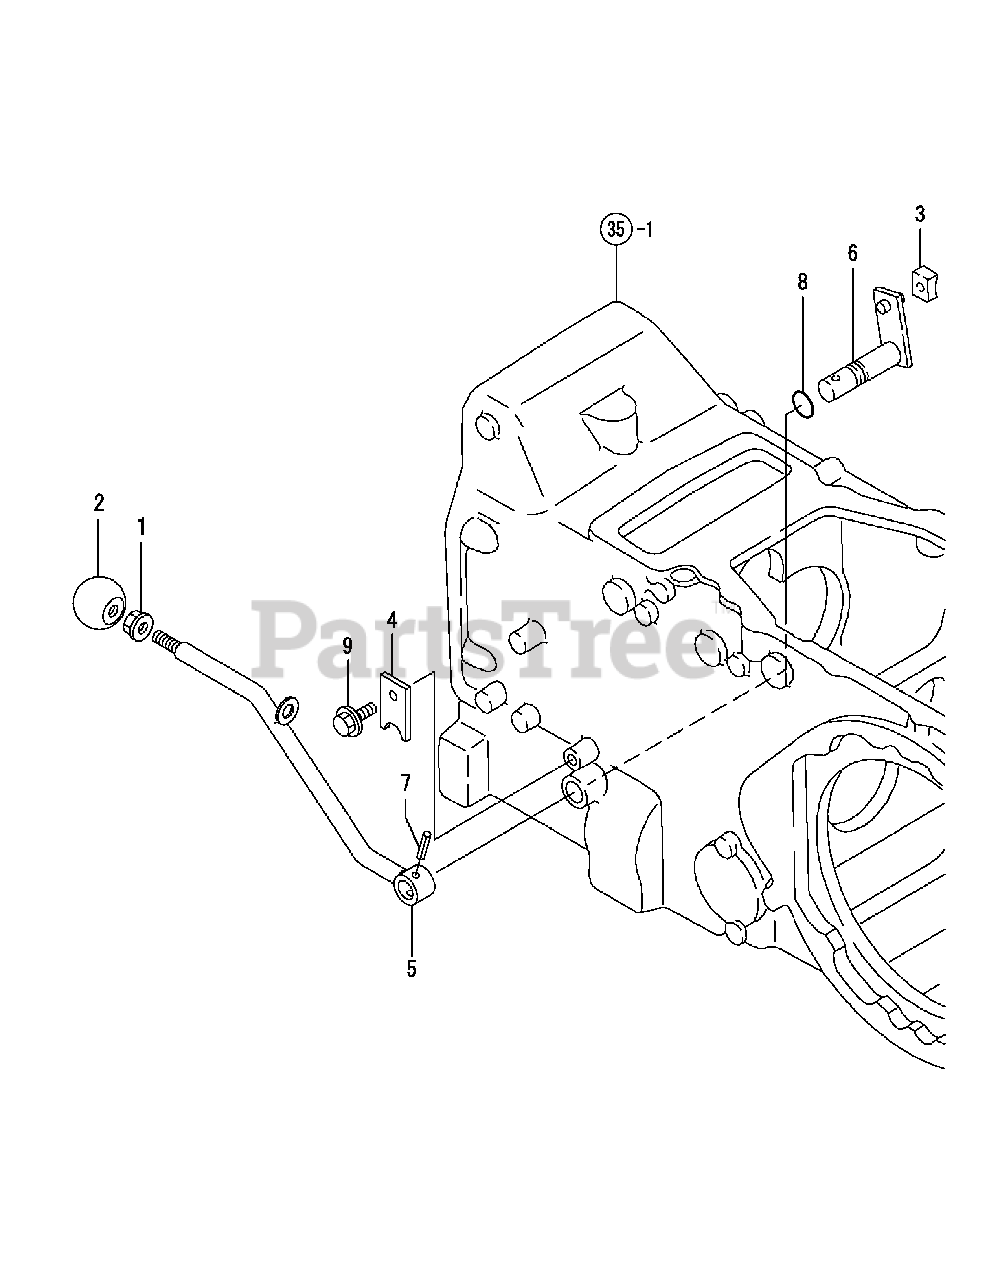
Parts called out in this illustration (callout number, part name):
1	NUT W/WASHER 10
5	LEVER,FRONT SHIFT
6	ARM, FRONT SHIFT
7	SPRING PIN 6X32
8	O-RING 1A P-12.5
9	BOLT M 8X 16 PLATED
